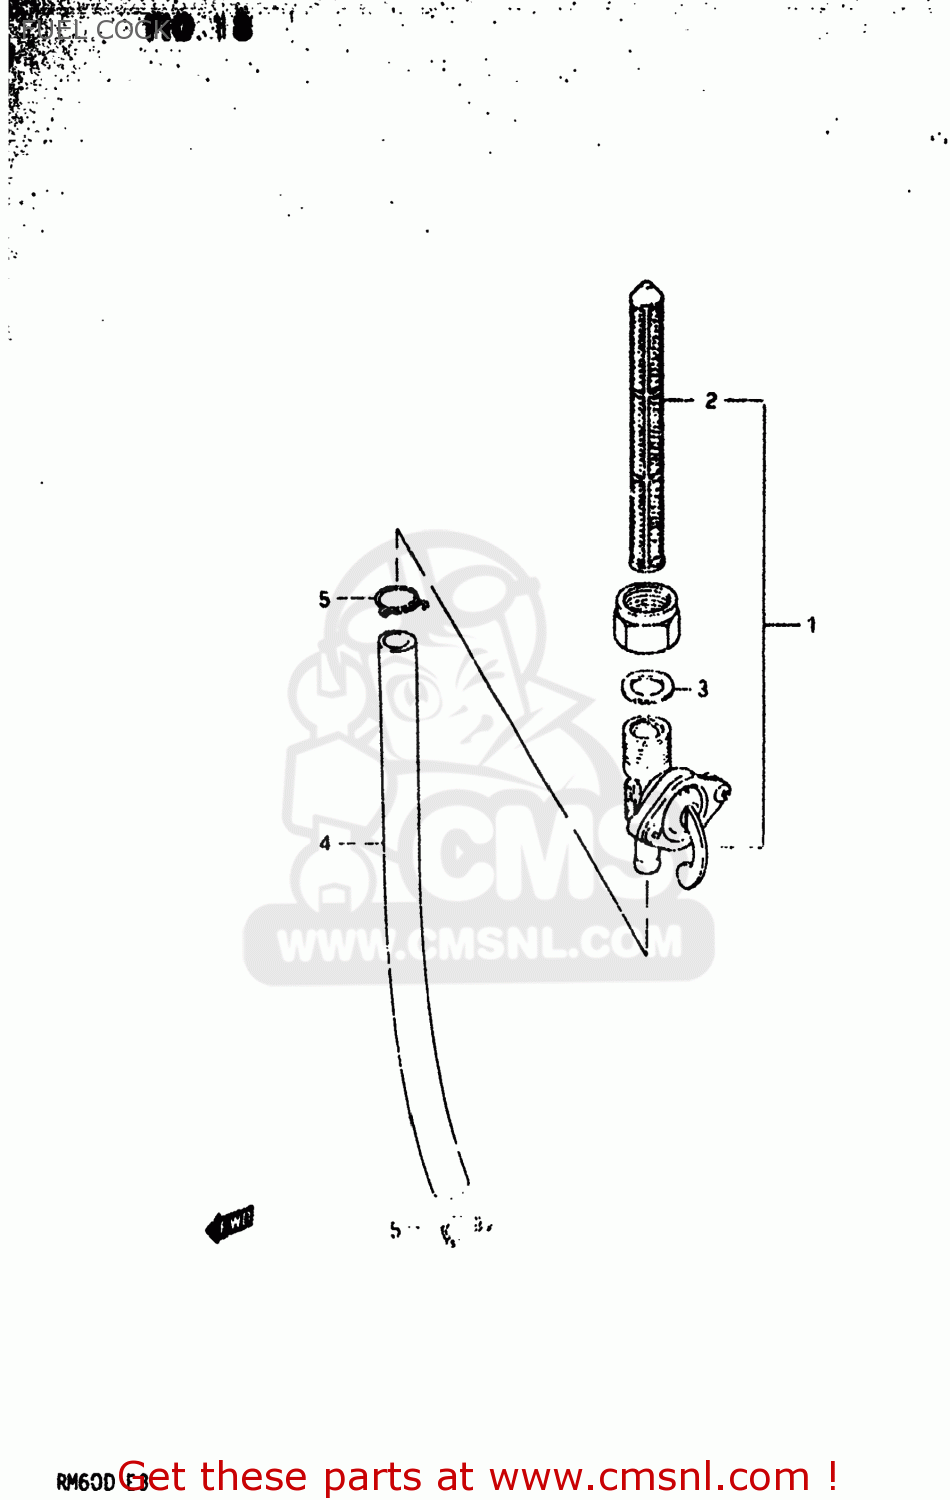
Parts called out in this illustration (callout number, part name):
1	COCK ASSY,FUEL
2	FILTER,FUEL
3	GASKET,FUEL COCK (NAS)
4	HOSE
5	CLIP
